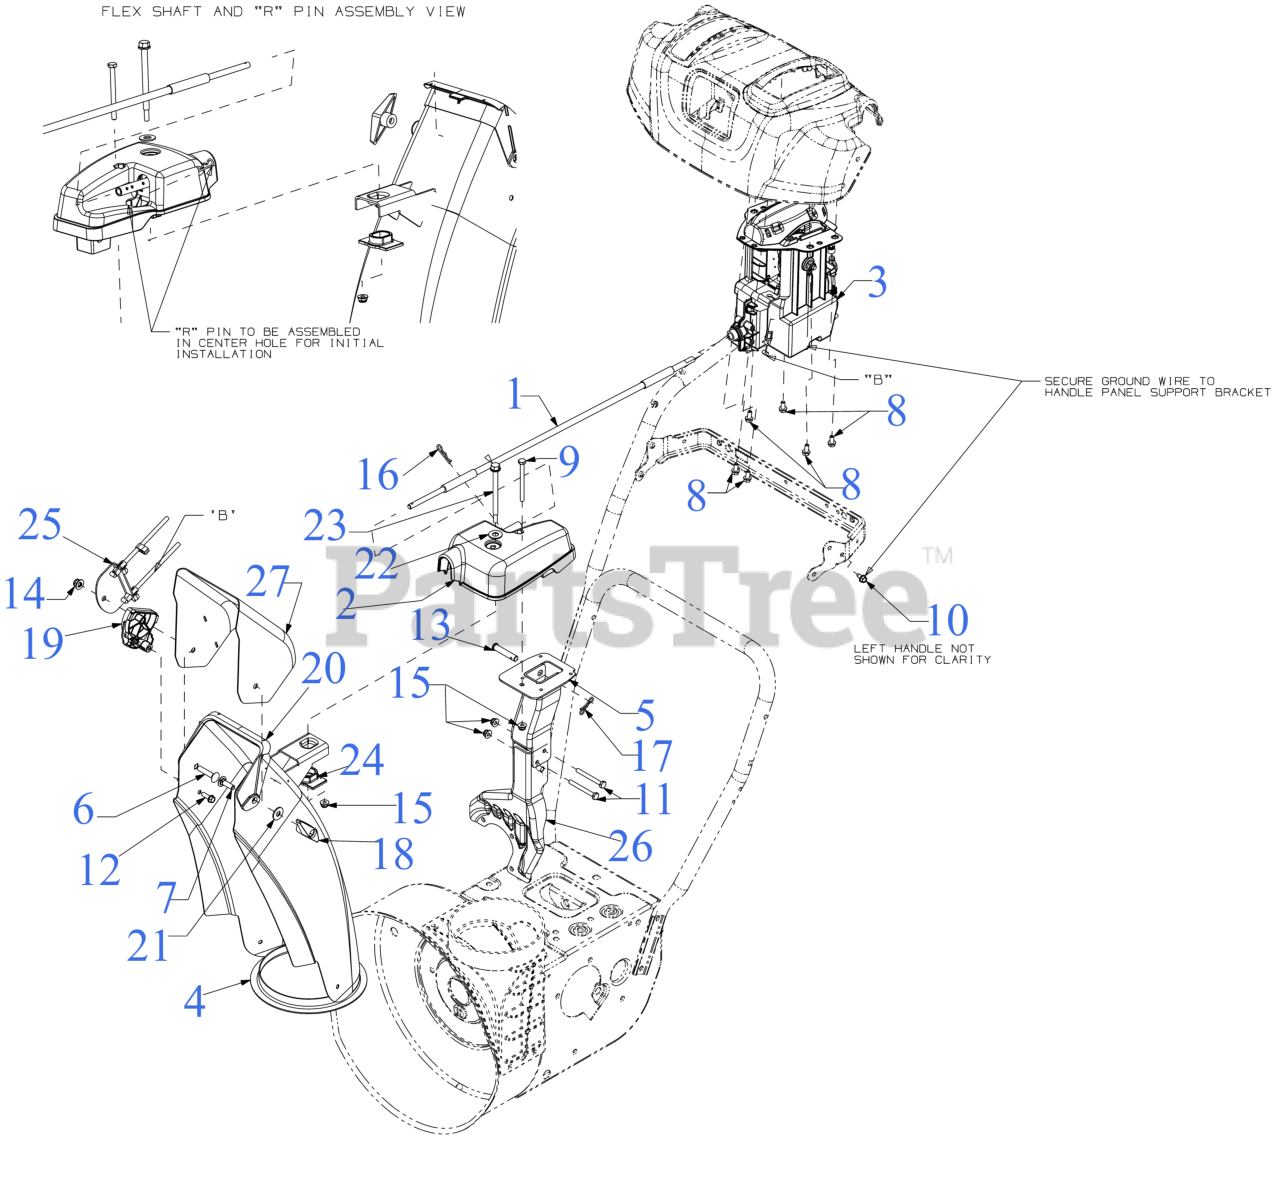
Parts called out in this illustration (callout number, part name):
1	ELECTRIC 4-WAY CHUTE CONTROL SHAFT
2	CHUTE GEARBOX ASSEMBLY
3	CHUTE CONTROL ASSEMBLY-4-WAY ELECTRIC
4	LOWER STEEL CHUTE 6" DIA
5	EXTENSION CHUTE MAST
6	CARRIAGE BOLT 5/16-18 x 1.50
7	CARRIAGE BOLT 5/16-18 x 1.00
8	HEX SCREW 1/4-15 x .50
9	SCREW 1/4-20 x 3.0 GR5
10	SCREW 1/4-20 X.500
11	SCREW 1/4-20 x 2.25 GR5
12	SCREW 1/4-15 x .750
13	CLEVIS PIN 3/8 x 1.87
14	FLANGE LOCK NUT 5/16-18
15	FLANGE LOCK NUT
16	INTERNAL COTTER PIN
17	BOW TIE COTTER PIN 1/4-5/16
18	WING KNOB NUT
18	STAR KNOB 5/16-18
19	CHUTE TILT GUIDE
20	UPPER CHUTE ADAPTER
21	FLAT WASHER
22	FLAT WASHER
23	SHOULDER SCREW
24	HELICAL GEAR CHUTE ADAPTER
27	UPPER STEEL CHUTE (REMOTE TILT)
